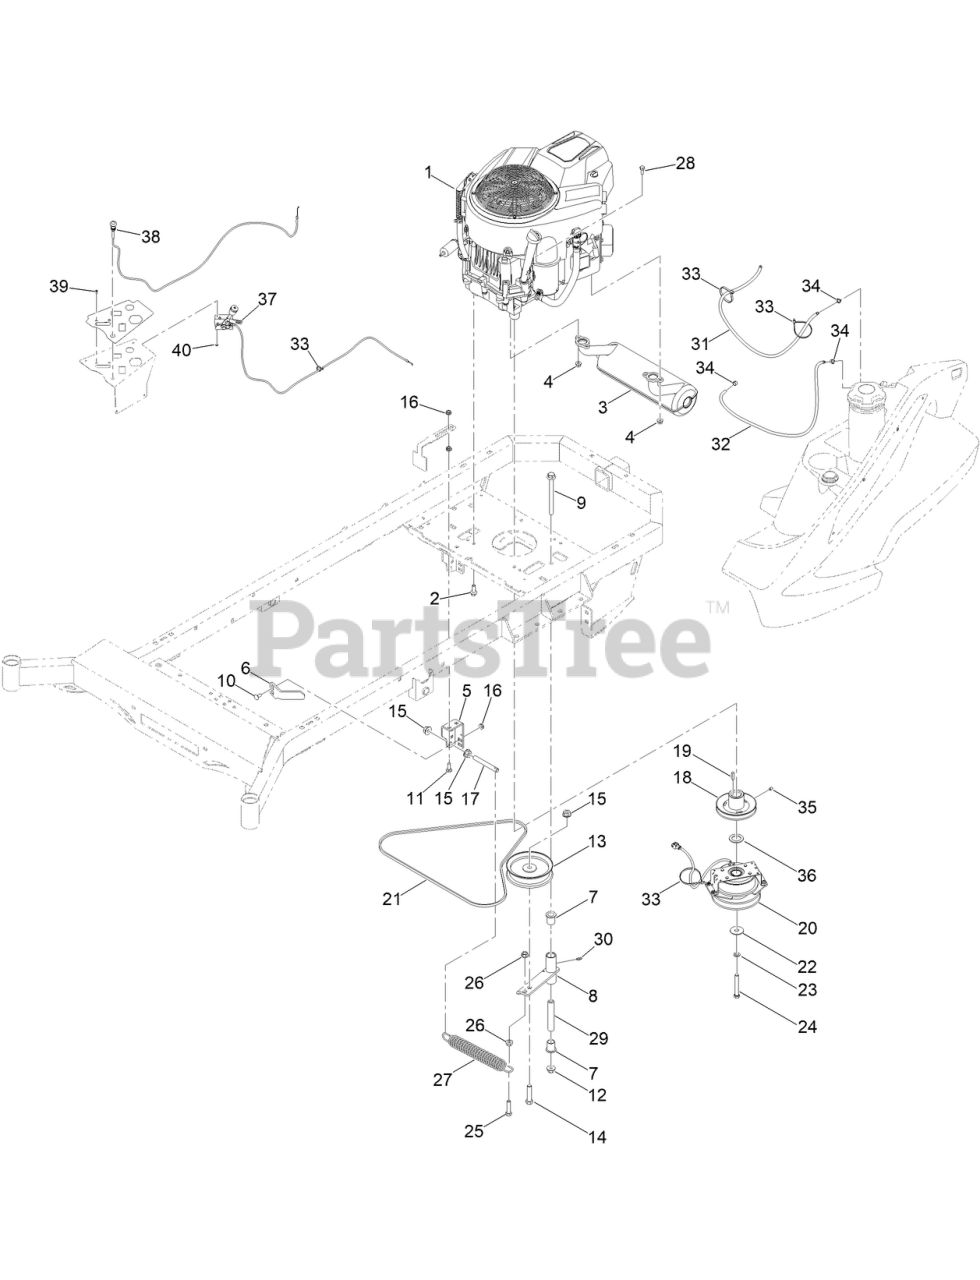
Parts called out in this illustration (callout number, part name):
1	27HP BRIGGS CXI ENGINE
2	3/8-16 X 1-1/8 IND HWH W/SERR TRI LOB ZY
3	EXHAUST SYST BRIGGS 25/ 27HP ENGNS
4	NUT-HF
5	MWR PUMP IDLER TENSIONING BRKT BLACK
6	2021 TTQ MOWER OGURA CLUTCH BRACKET
7	3/4IN ID X15/16IN OD X 1-1/8IN FLNG BUSH
8	MWR PUMP IDLER ASSY BLACK
9	1/2-13 X 5-1/2 HEX FLANGE BOLT GR 8 ZY
10	BOLT-CARR
11	5/16-18 X 1-1/4 CARRIAGE BOLT ZC/YEL
12	NUT-LOCK
13	5-3/4IN IDLER PULLEY 7/16IN SPACER ASSY
14	SCREW-HH
15	NUT-HHF
17	MWR PUMP IDLER SPRING TENSIONER
18	MWR HYDRAULIC PUMP DRIVE PULLEYA BELT
20	MWR TTQ OGURA CLUTCH
21	MWR PUMP BELT RT A X 68.25IN EFF LNGTH
22	1/2IN X 1-5/8 BELLEVILLE CUP WASHER YZ
23	WASHER-LOCK
24	TTQ CLUTCH BOLT
26	NUT-HF
27	MWR DECK SPRING
28	M8-1.25 X 20MM HEX FLANGE BOLT ZINC 10.9
29	MWR INNER IDLER SPACER
30	1/4IN DRIVE TYPE GREASE FITTING YZ
31	MWR FUEL TANK BLACK 3/16IN VENT TUBE 1FT
32	1/4IN SAE J30R7 BULK HOSE 1FT
33	TIE-CABLE
34	1/2IN (#8) HOSE CLAMP
35	5/16-18 X 3/8 SOCKET SET SCREW
36	WASHER-THRUST
37	MWR THROTTLE CABLE ASSY W / HANDLE
38	MWR CHOKE CABLE ASSM
39	10-24 X 1/2 SOCKET C/S 18-8 SS
40	NUT-LOCK
